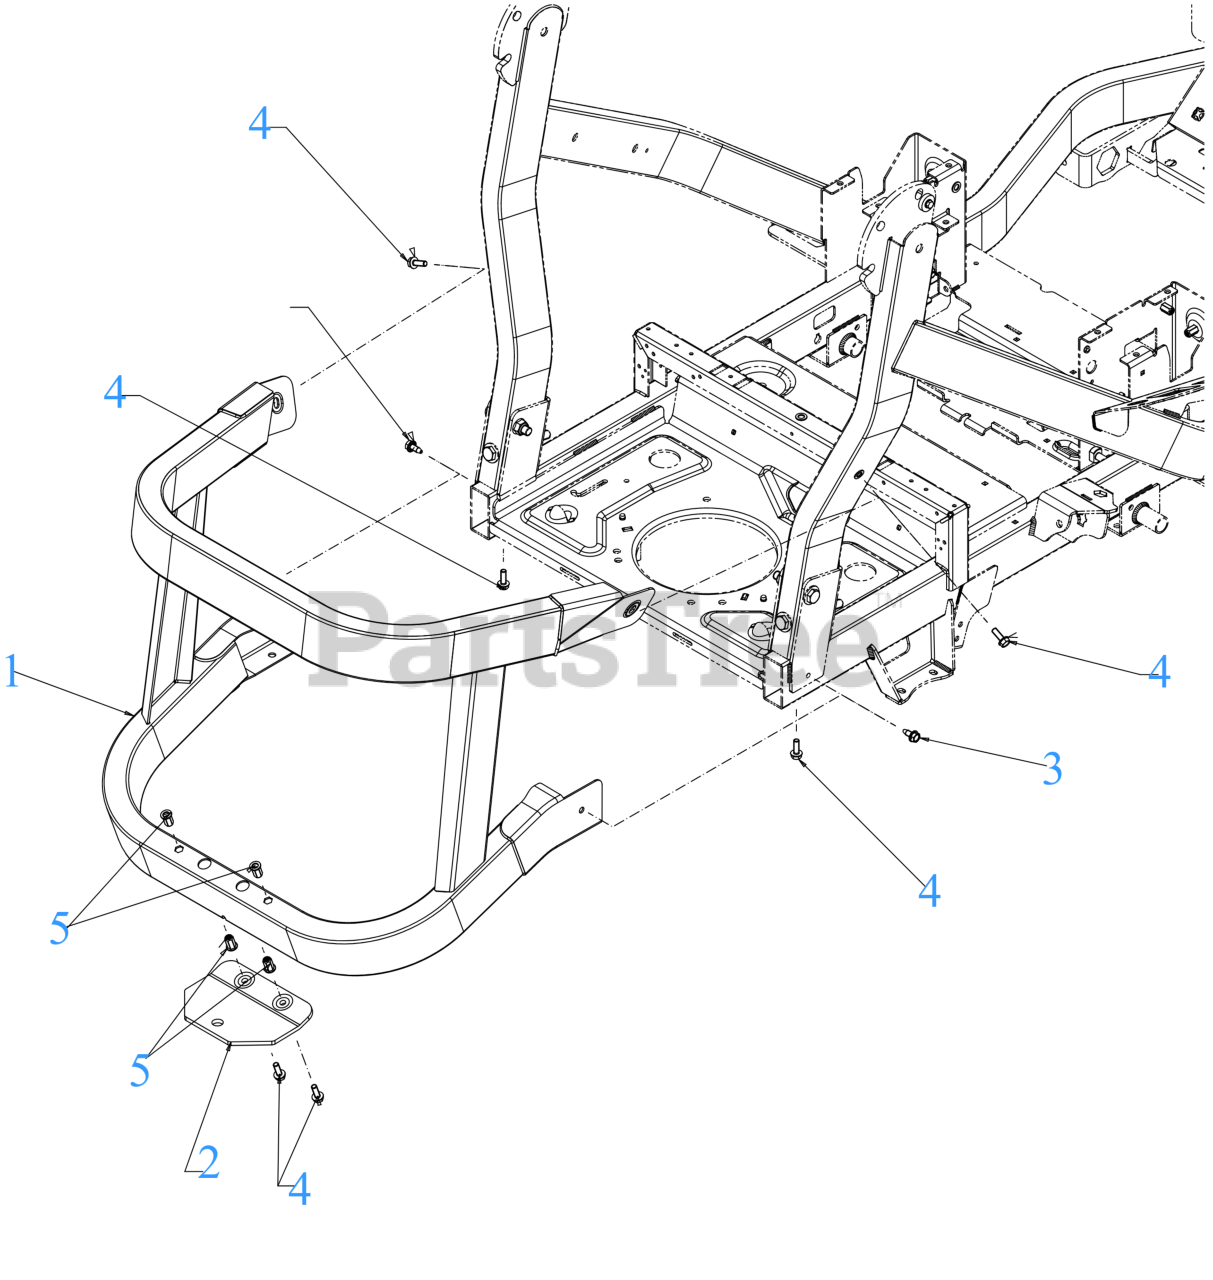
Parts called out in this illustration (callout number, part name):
1	FRAME (REAR)
2	HITCH PLATE
3	SCREW M8-1.25 x .750
4	SCREW 5/16-18 x .875 GR5
5	NUT RIVET 5/16-18
